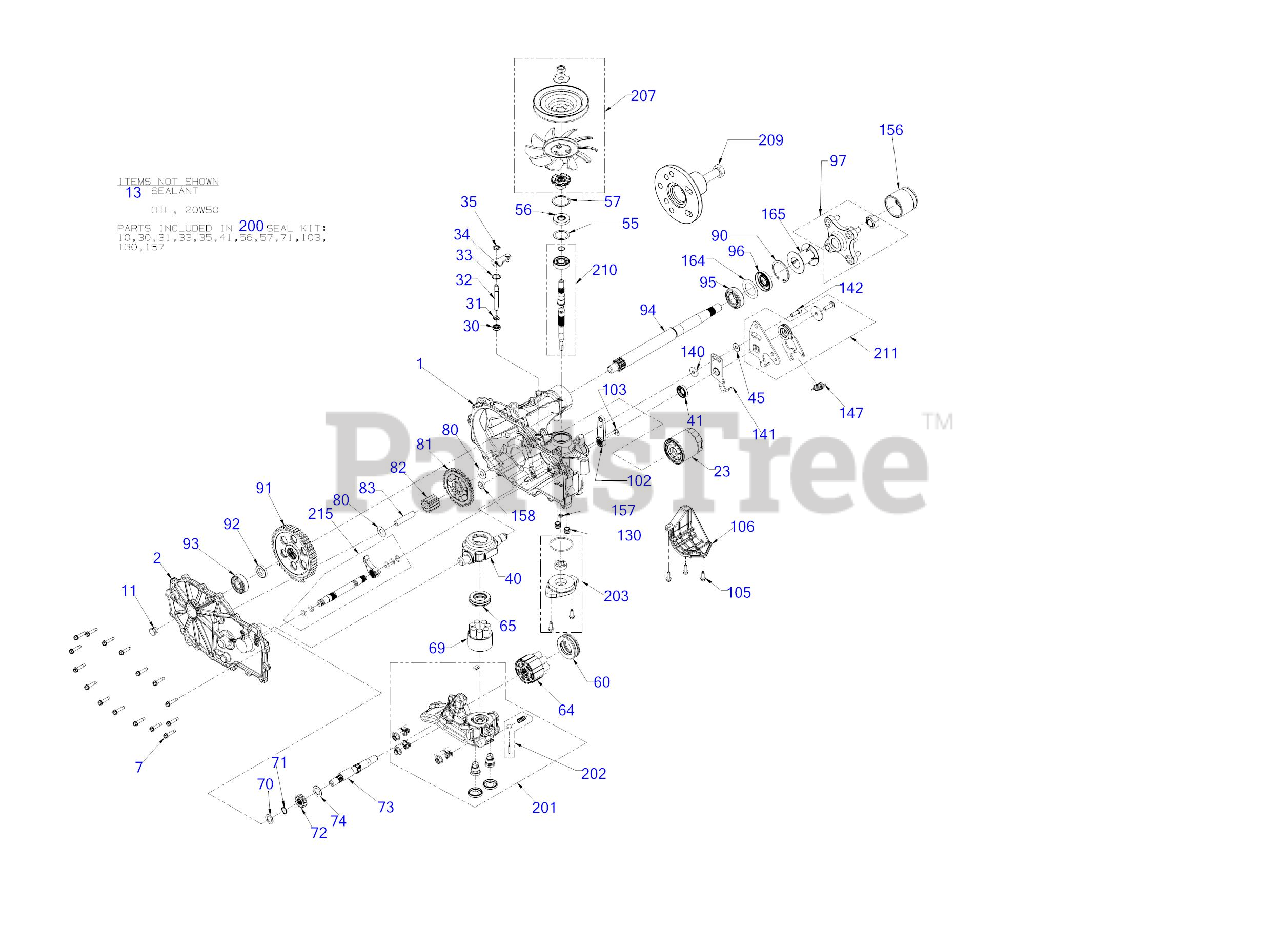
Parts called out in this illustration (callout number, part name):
1	KIT - HOUSING MAIN LH CNTL
2	KIT - SIDE COVER LH
7	SCREW-WASHER HEAD
11	VENT PLUG
13	SEALANT-HOUSING
23	FILTER-OIL
30	SEAL-LIP .375
31	RETAINING RING
32	BYPASS RODS
33	RETAINING RING
34	ARM-BYPASS
35	RETAINING RING
40	SWASHPLATE-TRUNNION
45	FLAT WASHER
55	WASHER 1.23X1.56X
57	RETAINING RING
60	THRUST BEARING
64	BLOCK ASSEMBLY-CYLINDER
65	THRUST BEARING
69	BLOCK KIT-CYLINDER
70	FLAT WASHER
71	RETAINING RING
72	GEAR - 13 TOOTH STEEL
73	MOTOR SHAFT
74	MOTOR SHAFT WASHER
81	GEAR - 46 TOOTH
82	GEAR-11 T
83	PIN-JACKSHAFT
90	RETAINING RING
91	GEAR - 54 TOOTH
92	SPACER .75X1.32X.257
93	BALL BEARING
94	AXLE SHAFT
95	BALL BEARING
97	HUB KIT-4 BOLT
102	BRAKE LEVER
103	RETAINING RING EXT .438
106	GUARD-FILTER (LH)
130	TUBE-CHARGE TRIPLE O-RING
140	SPACER .32 x 1.005 x .179
141	ARM-NEUTRAL (LH)
142	SCREWS KIT-RTN
147	EXTENSION SPRING
157	KIT-GEROTOR SEAL
158	MAGNET-RING
165	TUBE-AXLE 2.03
200	KIT - SEAL
201	CENTER SECTION KIT (LH)
202	KIT-CHARGE RELIEF
203	CHARGE KIT
207	FAN & PULLEY KIT
209	PULLER KIT-HUB
210	INPUT SHAFT KIT
211	KIT - RETURN CCW
215	INBOARD KIT
